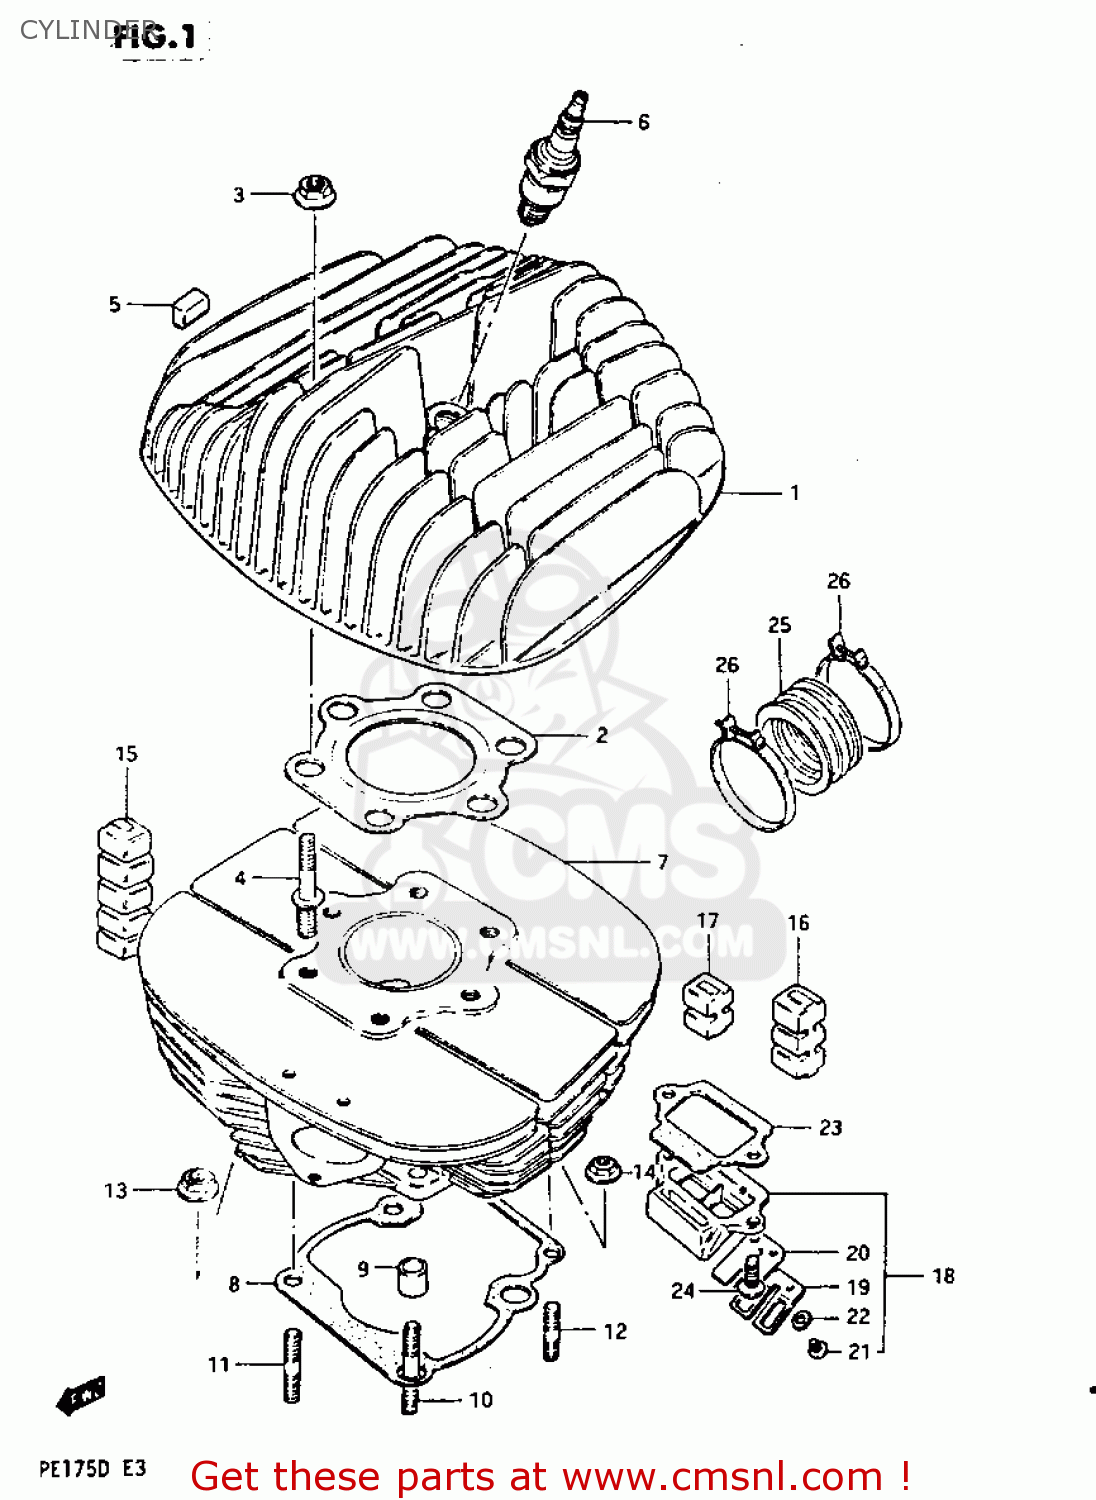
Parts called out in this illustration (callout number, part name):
1	HEAD,CYLINDER
2	GASKET,CYLINDER HEAD (NAS)
3	NUT
4	BOLT,STUD
5	PAD,CYLINDER
6	PLUG,SPARK(B10EGV)
7	CYLINDER
8	GASKET,CYLINDER (MCA)
9	PIN
10	BOLT,STUD
11	STUD 8X25
12	STUD 6X25
13	NUT
14	NUT
15	PAD,CYLINDER
16	PAD,CYLINDER
17	PAD,CYLINDER
18	VALVE ASSY,REED
19	STOPPER,REED VALVE
20	VALVE,REED
21	SCREW
22	WASHER,LOCK
23	GASKET,REED VALVE (MCA)
24	SCREW
25	PIPE,INTAKE
26	CLAMP
